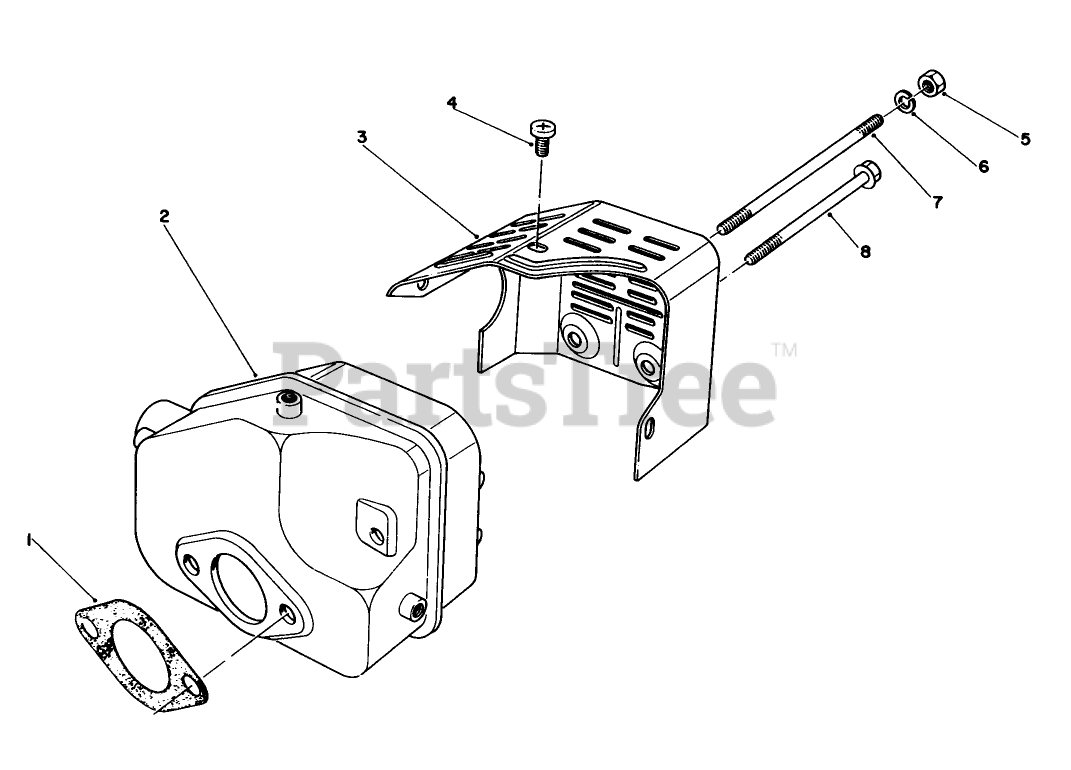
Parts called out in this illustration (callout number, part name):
1	GASKET
4	SCREW
6	WASHER-LOCK
